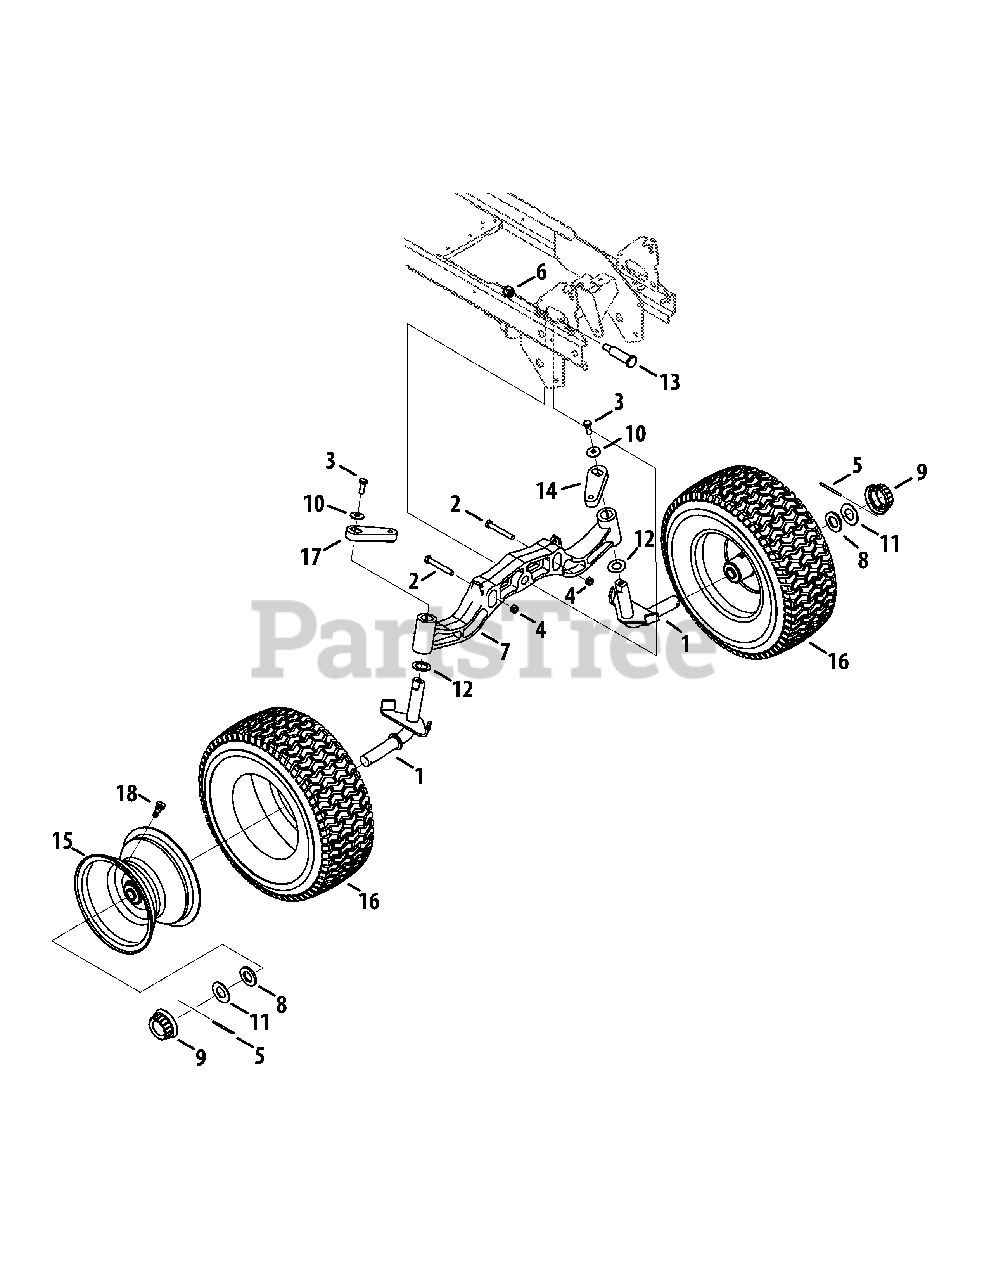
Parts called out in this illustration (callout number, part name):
1	Axle Assembly, 1"
2	Hex Screw, 3/8-16 x 2.75
3	Hex Cap Screw, 3/8-24 x 1.00
4	Hex Lock Nut, 3/8-16
5	Cotter Pin, 3/16 x 2.0
6	Hex Lock Nut, 1/2-13
7	Pivot Bar
8	Flat Washer, 1.010 x 1.75 x .172
10	Bevel Washer, .390 x 1.130 x .062
11	Flat Washer, 1.05 x 1.92 x .06
12	Thrust Washer, 1.010 x 1.56 x .060
13	Shoulder Screw, .750 x 2.23
14	Steering Arm, LH
15	Rim Assembly, 16.0 x 6.5 x 8
16	Tire, 16.0 x 6.50-8.00
17	Steering Arm, RH
18	Tubeless Air Valve
